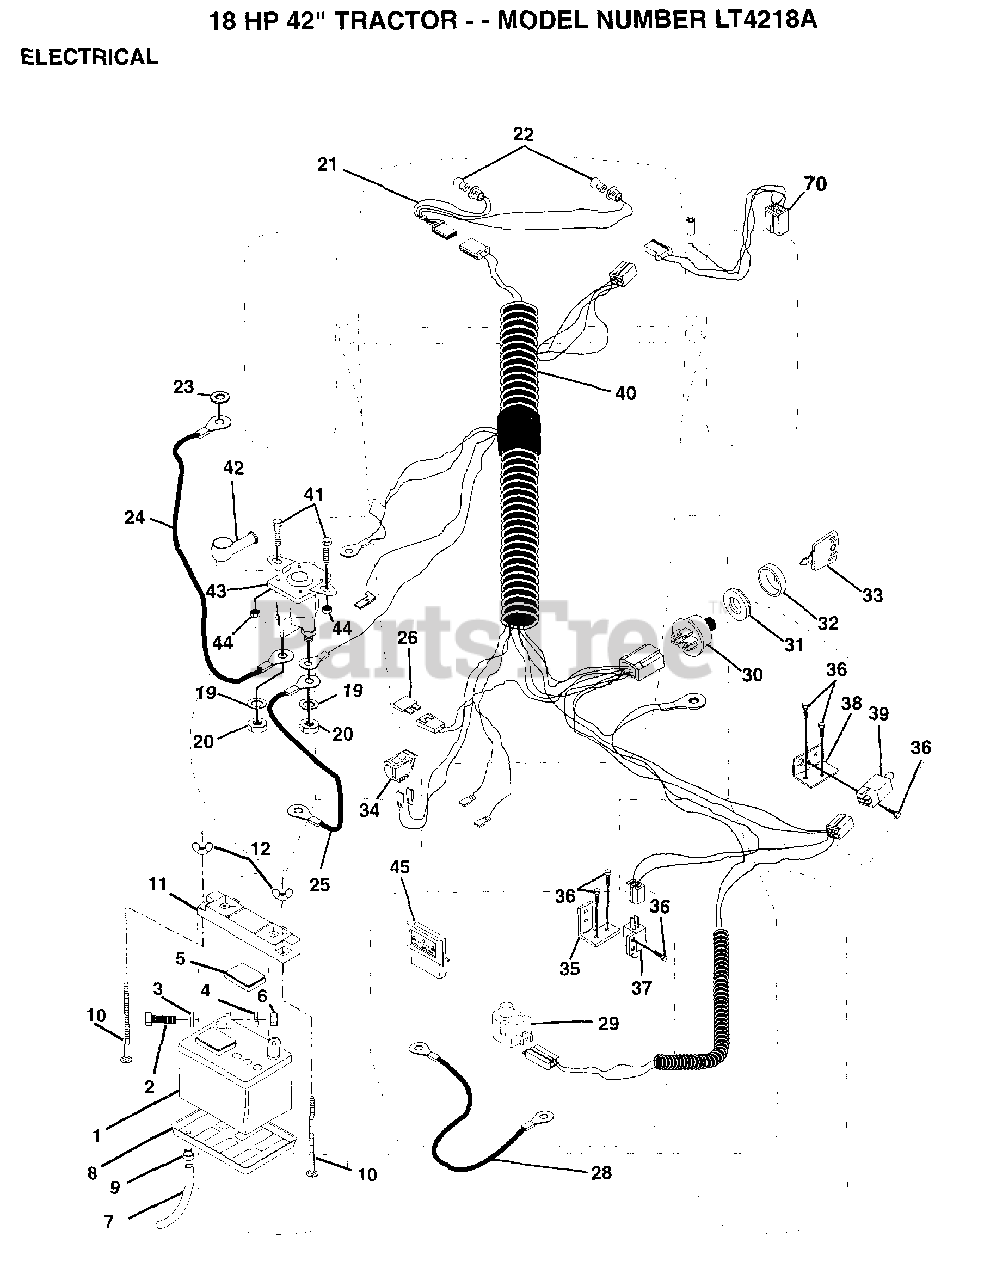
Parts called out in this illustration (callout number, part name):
2	BOLT LT
3	WASHER
4	LOCKWASHER
5	"CAP,BATTERY "
7	"DRAIN TU T, BATT"
8	"TRAY T, BATTERY"
9	HOSE CLAMP T
10	BOLT
20	NUT
21	"HARNESS,LIGHT SOC"
22	HEADLAMP BULB
23	LOCKWASHER
24	CABLE T
25	CABLE-BATTERY T
26	FUSE HYT
28	"CABLE T, BATTERY"
29	SWITCH SEAT
32	COVER KEY SWITCH
33	KEY MLD GEN DELTA
34	SWITCH LT
35	BRACKET LT
36	SCREW
37	SWITCH-INTER. GT
38	BRACKET SWITCH IN
39	SWITCH INTERLOCKT
40	HARNESS IGN DASH
41	BOLT HXHD FIN
44	NUT HXKEP 1/4X20
70	HARNESS ENG DUAL
